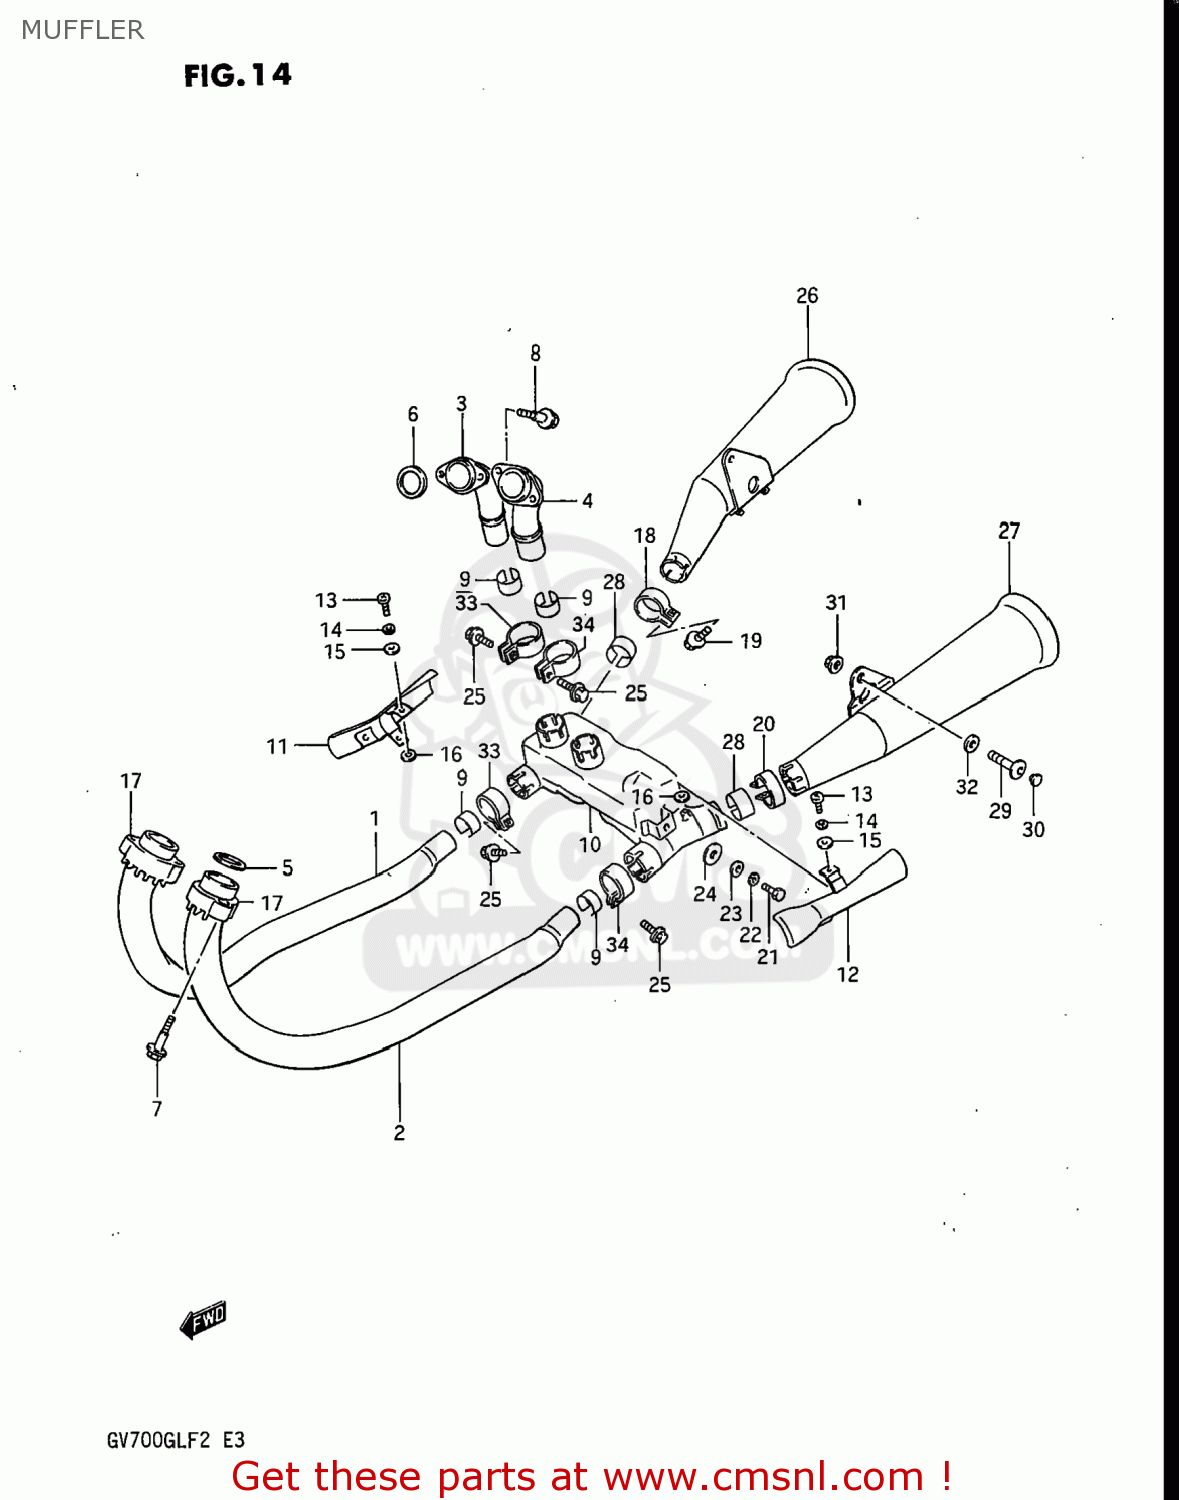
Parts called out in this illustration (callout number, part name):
1	PIPE,EXHAUST
2	PIPE,EXHAUST,FRONT,LEFT
3	FLANGE,EXHAUST PIPE
4	COVER,EXHAUST PIPE
5	GASKET,EXHAUST PIPE (NAS)
6	GASKET,EXHAUST PIPE (NAS)
7	BOLT
8	BOLT
9	CONNECTOR,MUFFLER
10	BODY,PRE MUFFLER
11	COVER,PRE MUFFLER,RIGHT
12	COVER,PRE MUFFLER,LEFT
13	SCREW 6X12
14	LOCK WASHER
15	WASHER
16	GASKET 6.2X12X1.5 (MCA)
17	CLAMP(H:21)
18	CLAMP,MUFFLER CONNECTOR
19	BOLT
20	CLAMP,MUFFLER CONNECTOR
21	BOLT
22	LOCK WASHER
23	WASHER
24	GASKET
25	BOLT
26	MUFFLER ASSEMBLY
27	MUFFLER ASSEMBLY
28	CONNECTOR,MUFFLER
29	BOLT
30	CAP
31	NUT
32	WASHER(10.5X20X3.2)
33	CLAMP,MUFFLER CONNECTOR
34	CLAMP,MUFFLER CONNECTOR
